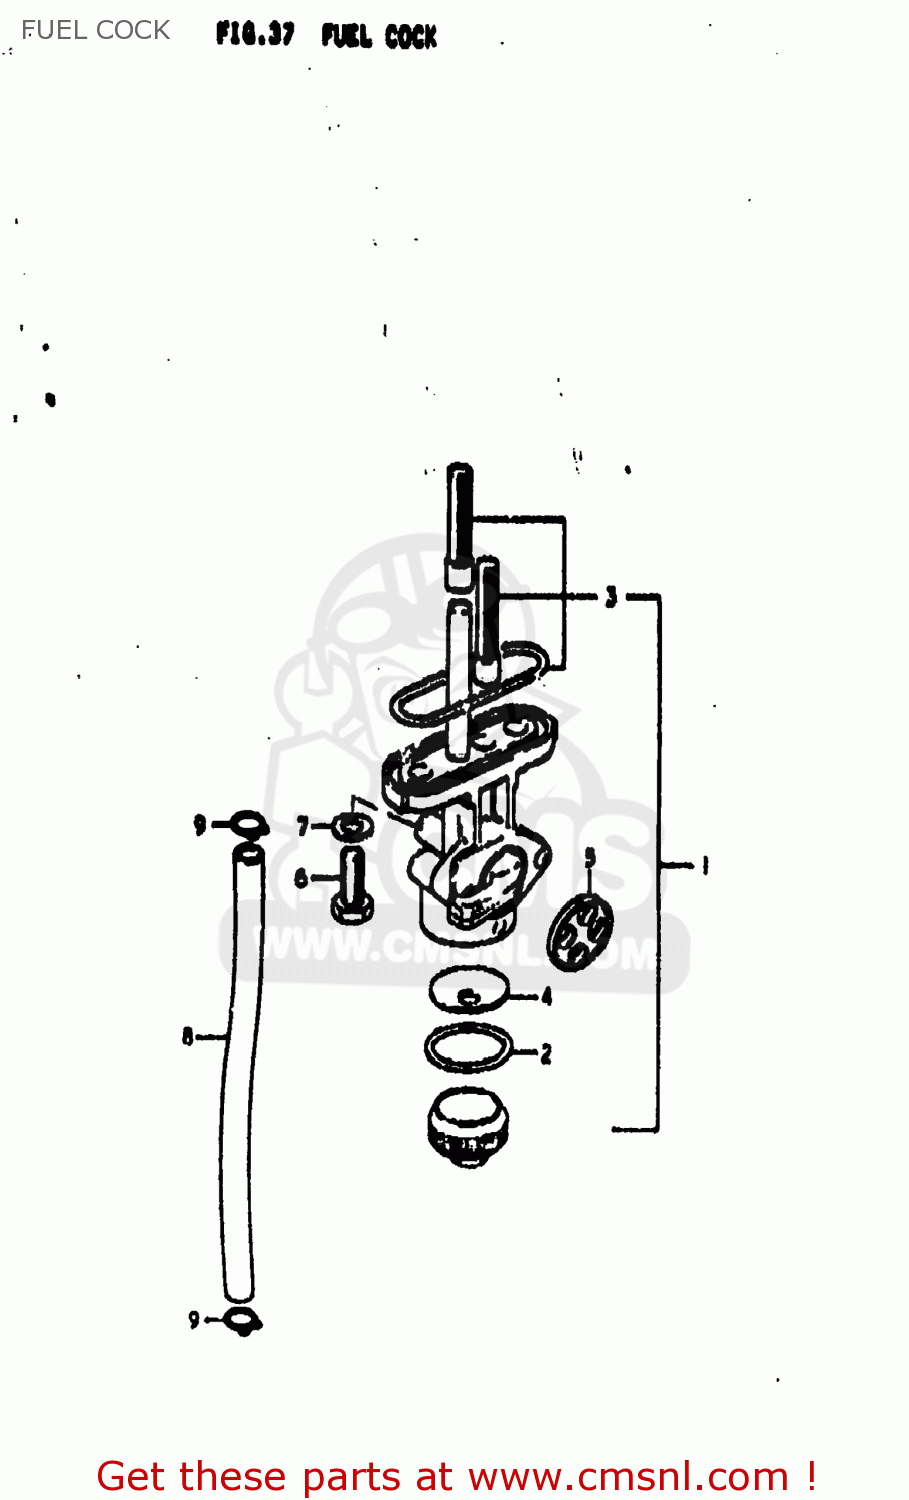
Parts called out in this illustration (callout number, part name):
1	COCK ASSEMBLY,FUEL
2	GASKET,FILTER (NAS)
3	FILTER SET,FUEL COCK
4	NET,STRAINER
5	GASKET,LEVER (NAS)
6	SCREW
7	GASKET
8	HOSE
9	CLIP
